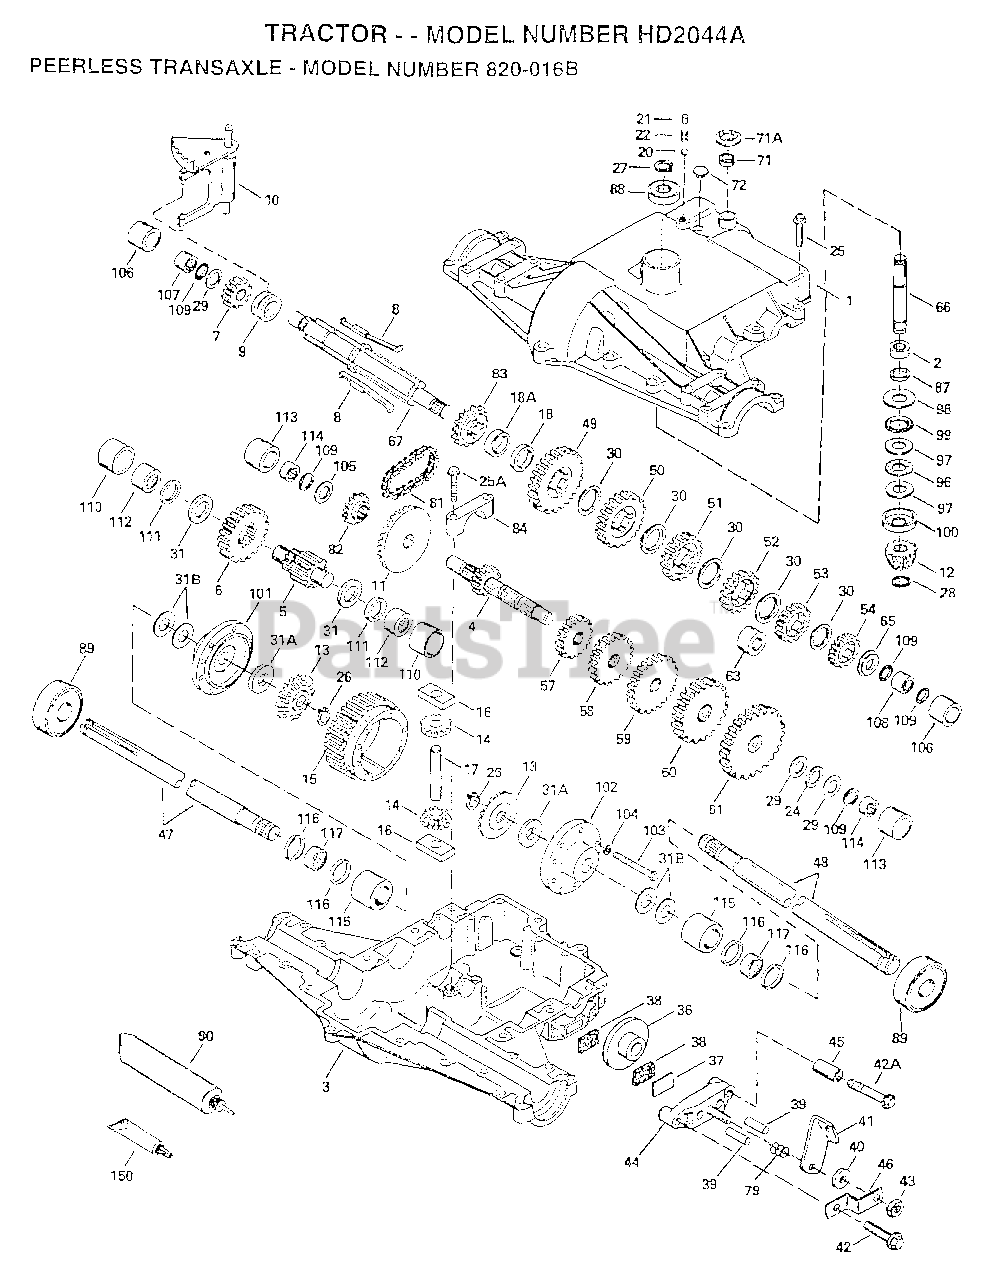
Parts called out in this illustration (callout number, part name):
1	COVER TRANSAXLE
2	BEARING NEEDLE
3	CASE TRANSAXLE
4	SHAFT COUNTER
5	SHAFT, OUTPUT, 9T
6	GEAR, OUTPUT, 35T
7	GEAR, SPUR, 15T
9	COLLAR SHIFT
10	ROD AND FORK ASSY SHIFT
11	GEAR BEVEL, 33T
12	BEVEL PINION, 13T
14	PINION, 10T
15	GEAR, RING, 31T
16	BLOCK DRIVE
18	SPACER, .350/.340 THICK
18A	SPACER, .276/.268 THICK
20	BALL STEEL, 5/16" DIA.
21	SCREW, 3/8-16 X 3/8"
24	THRUST BEARING
25	SCREW HEX HD 5/16-18 X 1-1/4
25A	SCREW, 1/4-20 X 1-1/4
28	RETAINING RING
29	WASHER THRUST
30	WASHER THRUST
31	WASHER THRUST
31B	WASHER THRUST
37	PLATE BRAKE PAD
41	LEVER BRAKE
42	SCREW, 1/4-20 X 1-1/4
42A	SCREW, 1/4-20 X 2-1/4
43	LOCKNUT 5/16-24
44	HOLDER BRAKE PAD
46	BRKT BRAKE LEVER
47	AXLE, 12-5/16" LONG
48	AXLE, 16-3/16" LONG
49	GEAR, SPUR, 41T
50	GEAR, SPUR, 35T
51	GEAR, SPUR, 30T
52	GEAR, SPUR, 25T
53	GEAR, SPUR, 22T
54	GEAR, SPUR, 19T
57	GEAR, SPUR, 15T
58	GEAR, SPUR, 20T
59	GEAR, SPUR, 25T
60	GEAR, SPUR, 28T
61	GEAR, SPUR, 31T
66	SHAFT INPUT
67	SHAFT BRAKE
71	SEAL SQUARE CUT
72	PLUG, THRDED, 9/16-18
81	CHAIN, ROLLER
82	SPROCKET 9T
83	SPROCKET 18T (REV)
84	BEARING CAP
87	OIL SEAL 3/4
88	BEARING BALL
89	BEARING BALL
90	GREASE BENTONITE, 32 OZ.
96	BEARING THRUST
97	WASHER THRUST
100	WASHER CUPPED
101	CARRIER DIFF THREADED HOLES
102	CARRIER DIFF
103	SCREW, 1/4-20 X 2-1/4
104	WASHER LOCK 1/4
107	BEARING NEEDLE
108	BEARING NEEDLE
110	SLEEVE STEPPED
111	RING SQ CUT
112	BEARING NEEDLE CAPPED
113	SLEEVE STEPPED
114	BEARING NEEDLE CAPPED
115	SLEEVE STEPPED
116	RING SQ CUT
117	BEARING NEEDLE
150	GASKET ELIMINATOR
